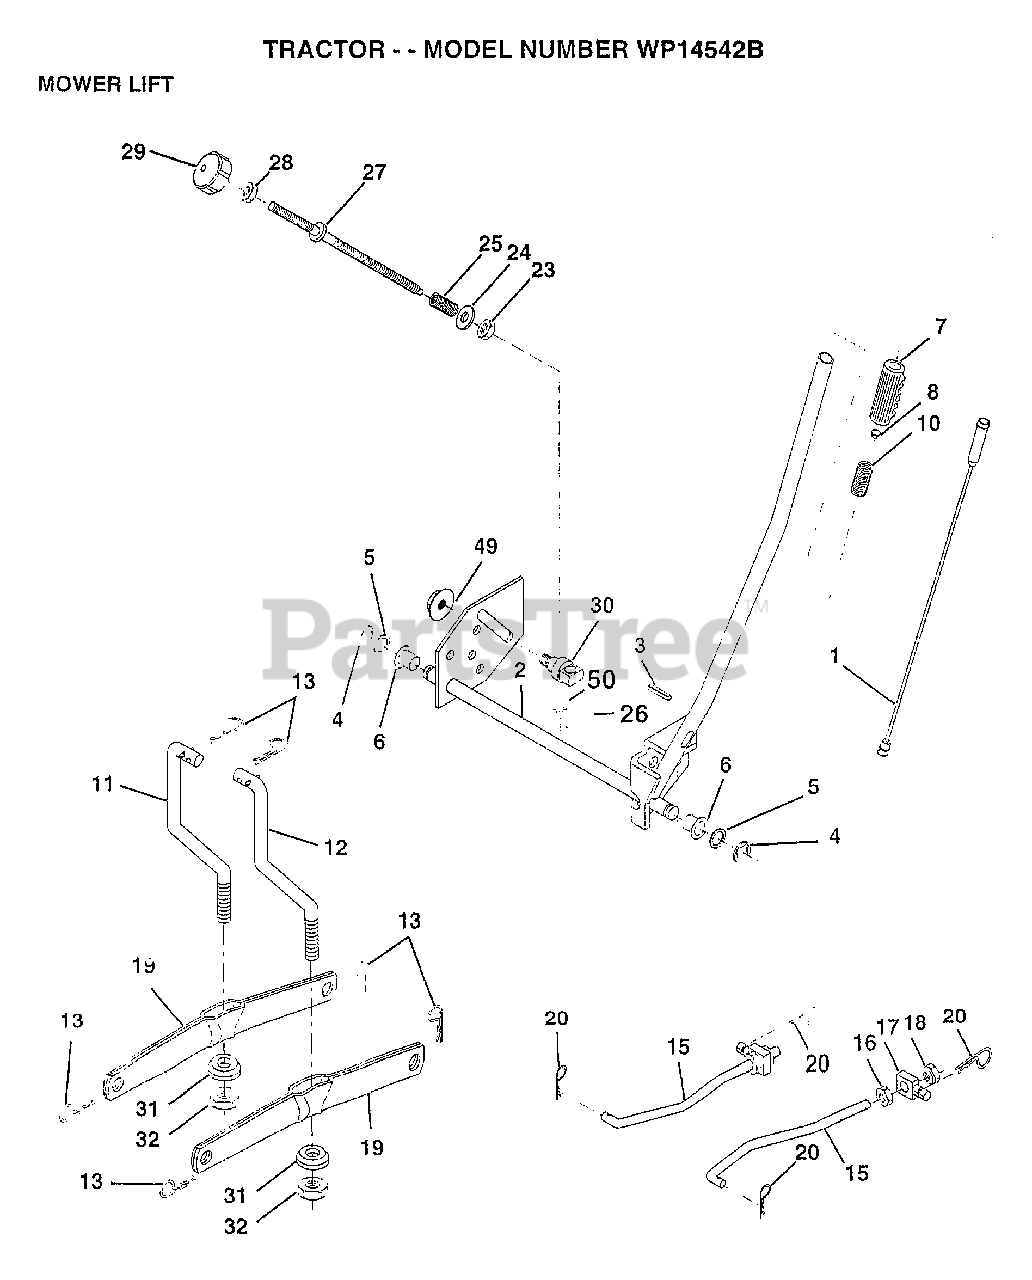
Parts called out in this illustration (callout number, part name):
1	WIRE.ASM.INNER
2	SHAFT.ASM.LIFT.RH
3	PIN GROOVE
5	WASHER
6	NYLON BEARING
7	GRIP
15	LINK.FRONT
16	NUT
17	TRUNION
18	NUT.LK.W/WSH.1/2.
19	ARM SUSP REAR
20	RETAINER.SPRING
23	NUT T
24	WASHER
25	SPRING.COMP.INF.H
27	ROD.ADJ.LIFT
28	NUT
29	KNOB INF 3/8-16
30	TRUNNION
31	BEARING PVT LH
32	NUT.CROWNLOCK.3/8
49	NUT.HXFLG.LOCK.
50	NUT PUSH M
